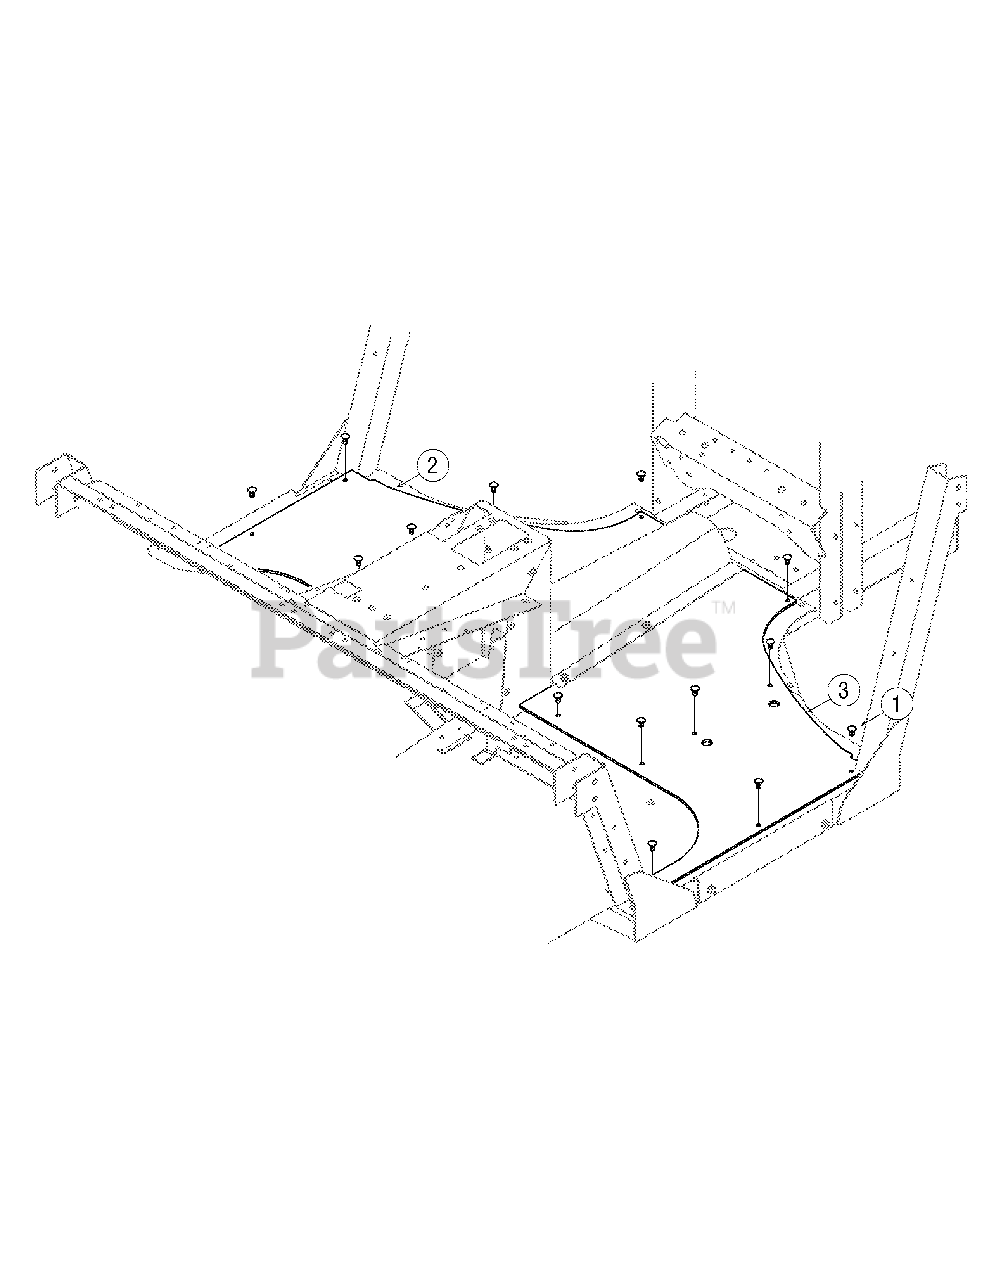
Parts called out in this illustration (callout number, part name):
1	Clip, Pnl, Ret
2	Mat, Floor - LH
3	Mat, Floor - RH
